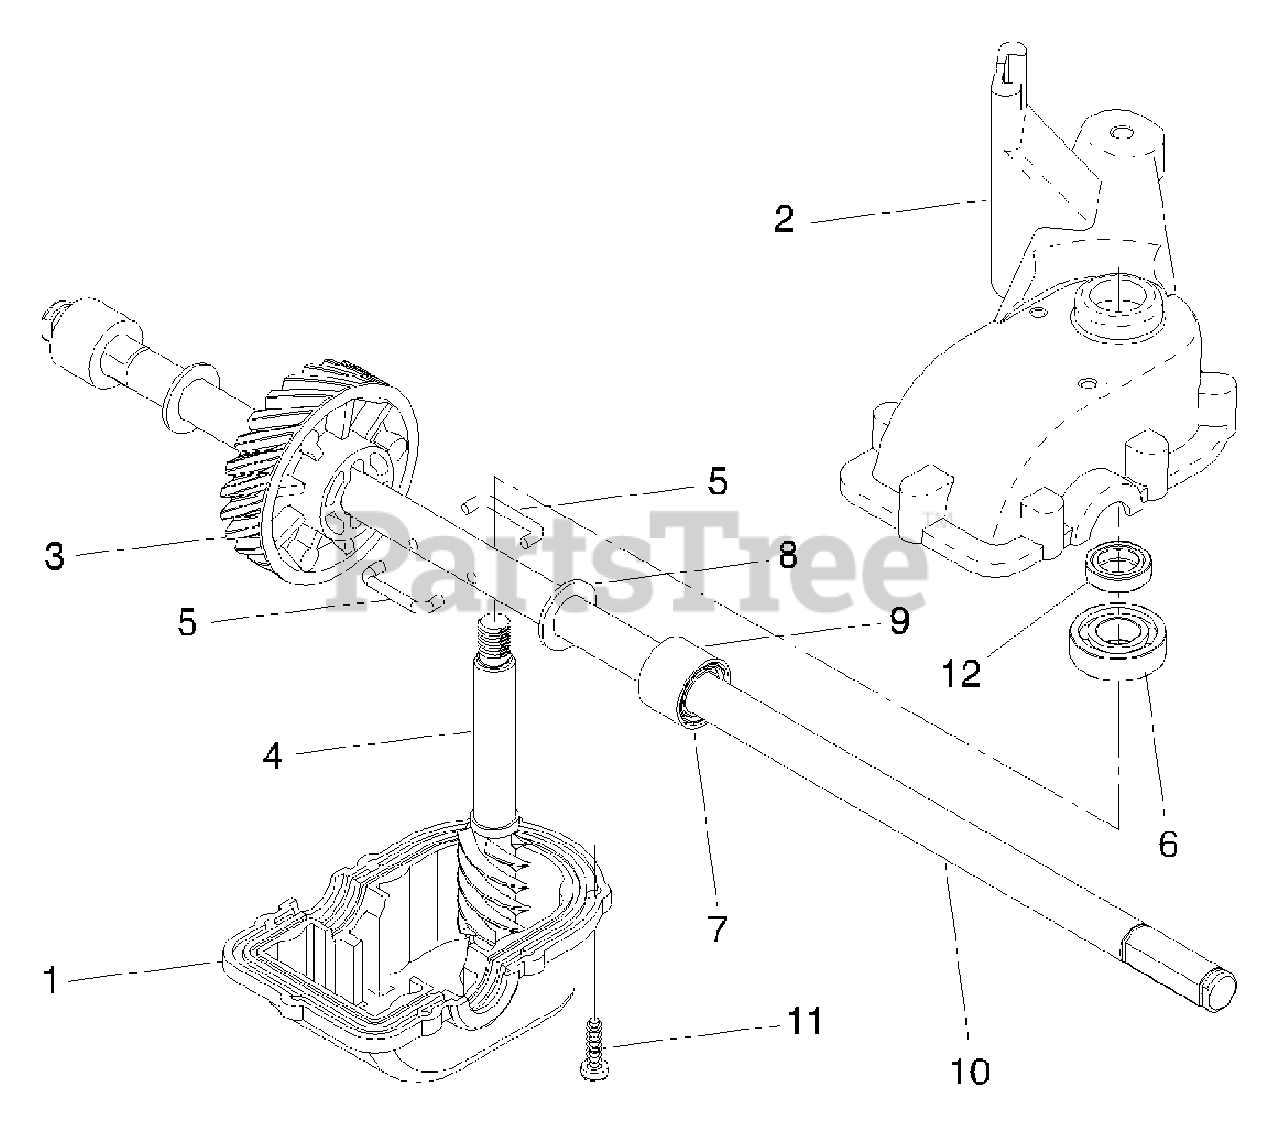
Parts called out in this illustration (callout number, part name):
1	Case, Lower
2	Case, Upper
3	Gear, 24 Teeth
4	Shaft, Input
5	Wire, Formed
6	Bearing, Ball
7	Seal, Output Shaft
10	Shaft, Output
12	Seal, Input Shaft
